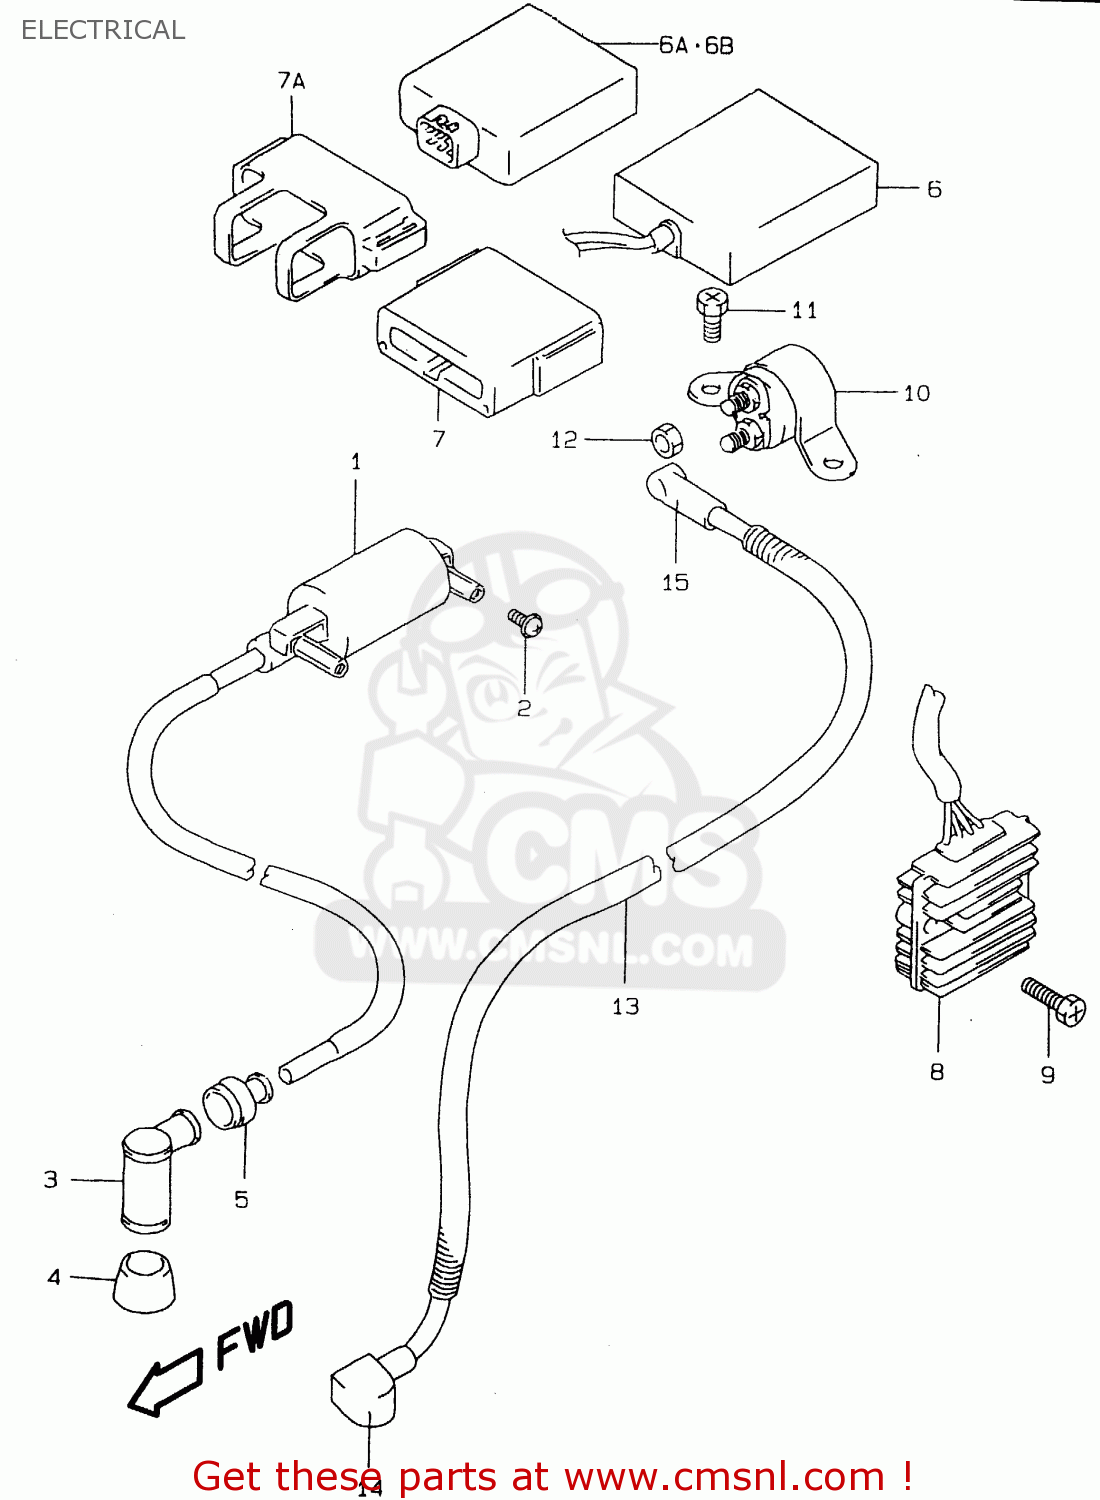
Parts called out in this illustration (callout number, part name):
1	COIL ASSY,IGNITION
2	SCREW
3	CAP,SPARK PLUG
4	SEAL,SPARK PLUG CAP
5	SEAL,HIGH TENSION CORD
6	CDI UNIT
6A	CDI UNIT
6B	CDI UNIT
7	CUSHION,CDI UNIT
7A	CUSHION,CDI UNIT
8	RECTIFIER ASSY
9	SCREW (6X25)
10	RELAY ASSY,STARTING MOTOR
11	SCREW(6X10)
12	NUT
13	WIRE,STARTER MOTOR LEAD
14	CAP,STARTER MOTOR TERMINAL
15	CAP,STARTER RELAY
